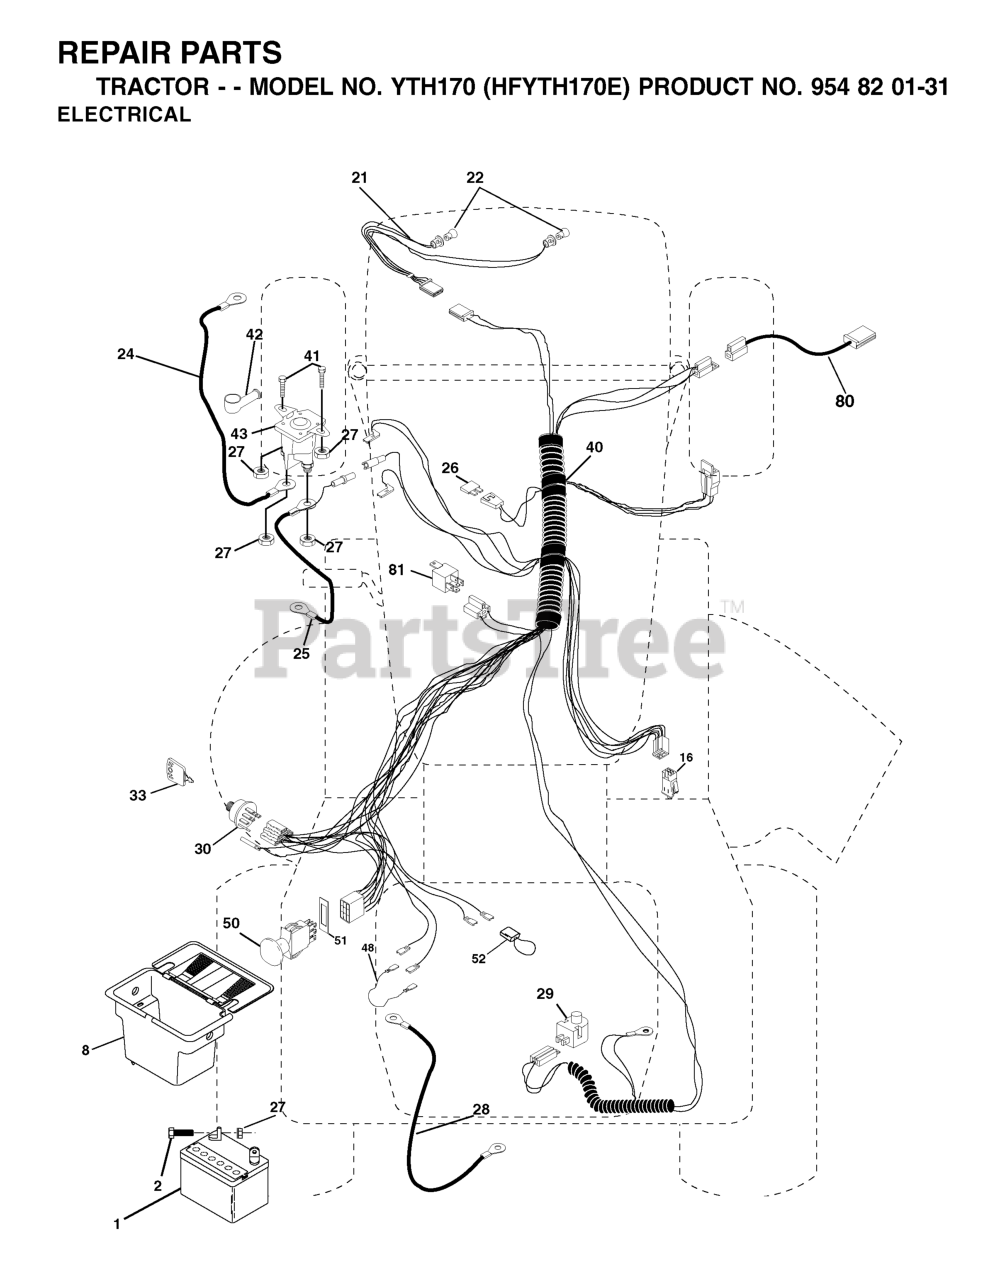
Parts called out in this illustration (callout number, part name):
1	BATTERY 12 VOLT 25 AMP
2	BOLT.HEX.1/4.X.3/4.DICHROMATE
8	CASE BATTERY MECH HINGE
16	SWITCH INTERLOCK
24	BATTERY CABLE GT
25	CABLE BATTERY
26	FUSE 20AMP
27	NUT
28	CABLE T
29	PLUNGER SWITCH (COLOR:OLIVE)
30	IGNITION SWITCH
33	KEY MLD GEN DELTA
40	HARNESS, ELEC IGNITION
41	BOLT
42	TERMINAL COVER
43	REPL BY 532 1461-54
48	ADAPTER.AMMETER
50	RP.PTO.SWITCH.8 TERMINAL.BLACK
51	FRAME RETAINING RING
52	WIRE PROTECTION LOOP
80	HARNESS, CLUTCH
81	RELAY.ASSY.T
